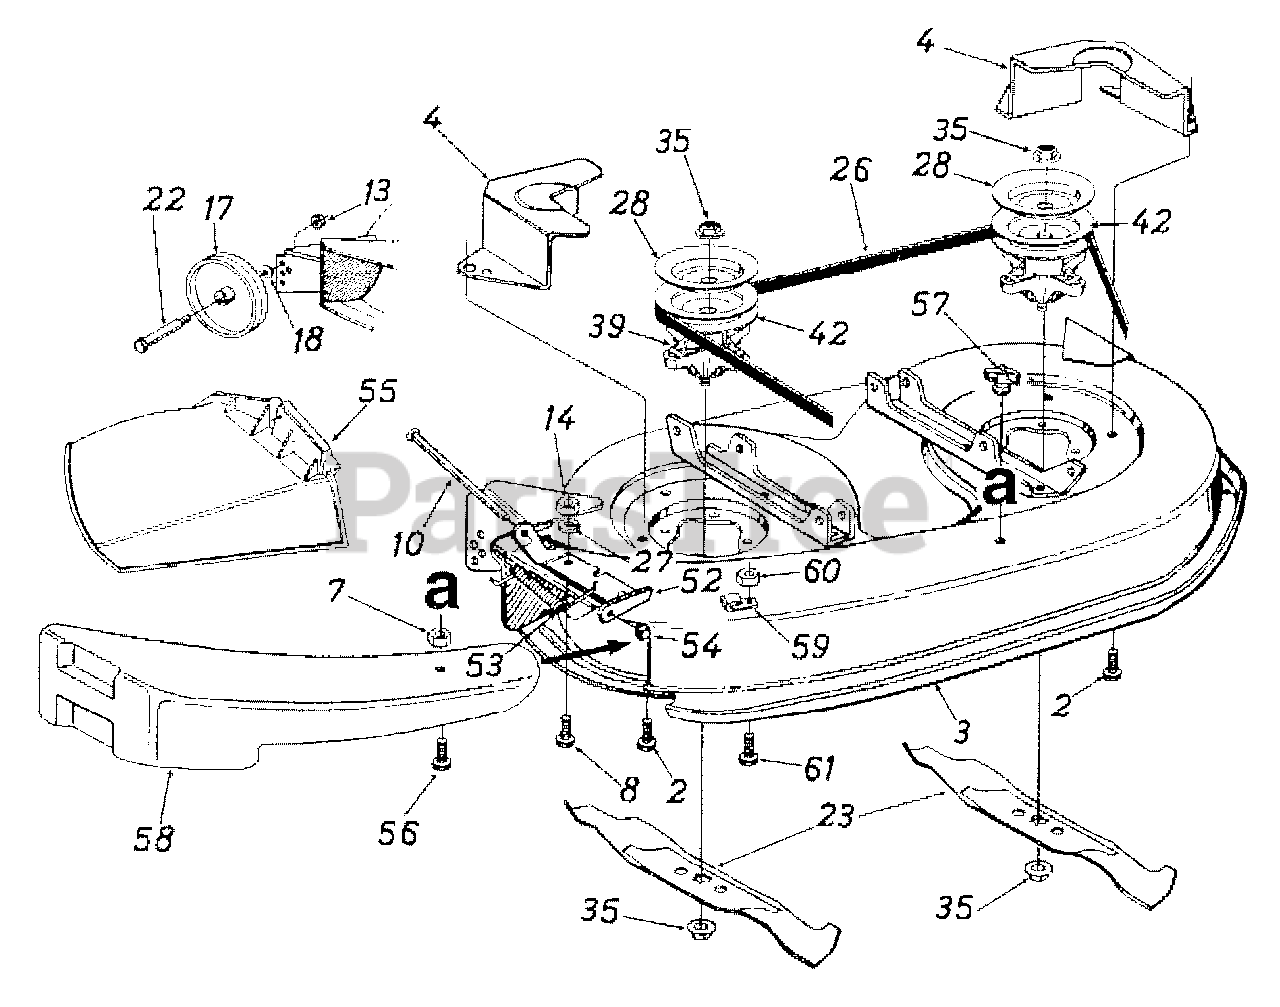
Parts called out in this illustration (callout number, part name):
2	Hex Washer: TT-Tap Scr. 5/16-18 x .75" Lg.
7	Hex Lock Nut 1/4-20 Thd.
8	Hex Bolt 1/4-20 x .62"
10	Hinge Pin
13	Hex Top Lock Nut 3/8-16 Thd.
14	Hex Nut 1/4-20 Thd. Gr. 5
17	Deck Wheel 5"
18	Bell Washer 0.40" I.D. x .88" O.D.
22	Shoulder Bolt .498" Dia. x 1.53"
23	3 in 1 Star Blade
26	V-Belt
27	Bell Washer 1/4" I.D.
28	Brake Disc
35	Hex Flange Nut 5/8-18 Thd.
39	Blade Spindle Ass'y.
42	5" Dia. Deck Pulley
52	Hinge Mtg. Bracket
53	Torsion Spring
55	Chute Ass'y. Comp.
56	Hex Bolt 1/4-20 x 1" Lg.
57	Wing Nut 1/4-20 Thd.
58	Mulching Plug
59	Retainer Hook Bracket
60	Hex Sems Nut 1/4-20 Thd.
61	Hex Bolt 1/4-20 x .62" Lg.
